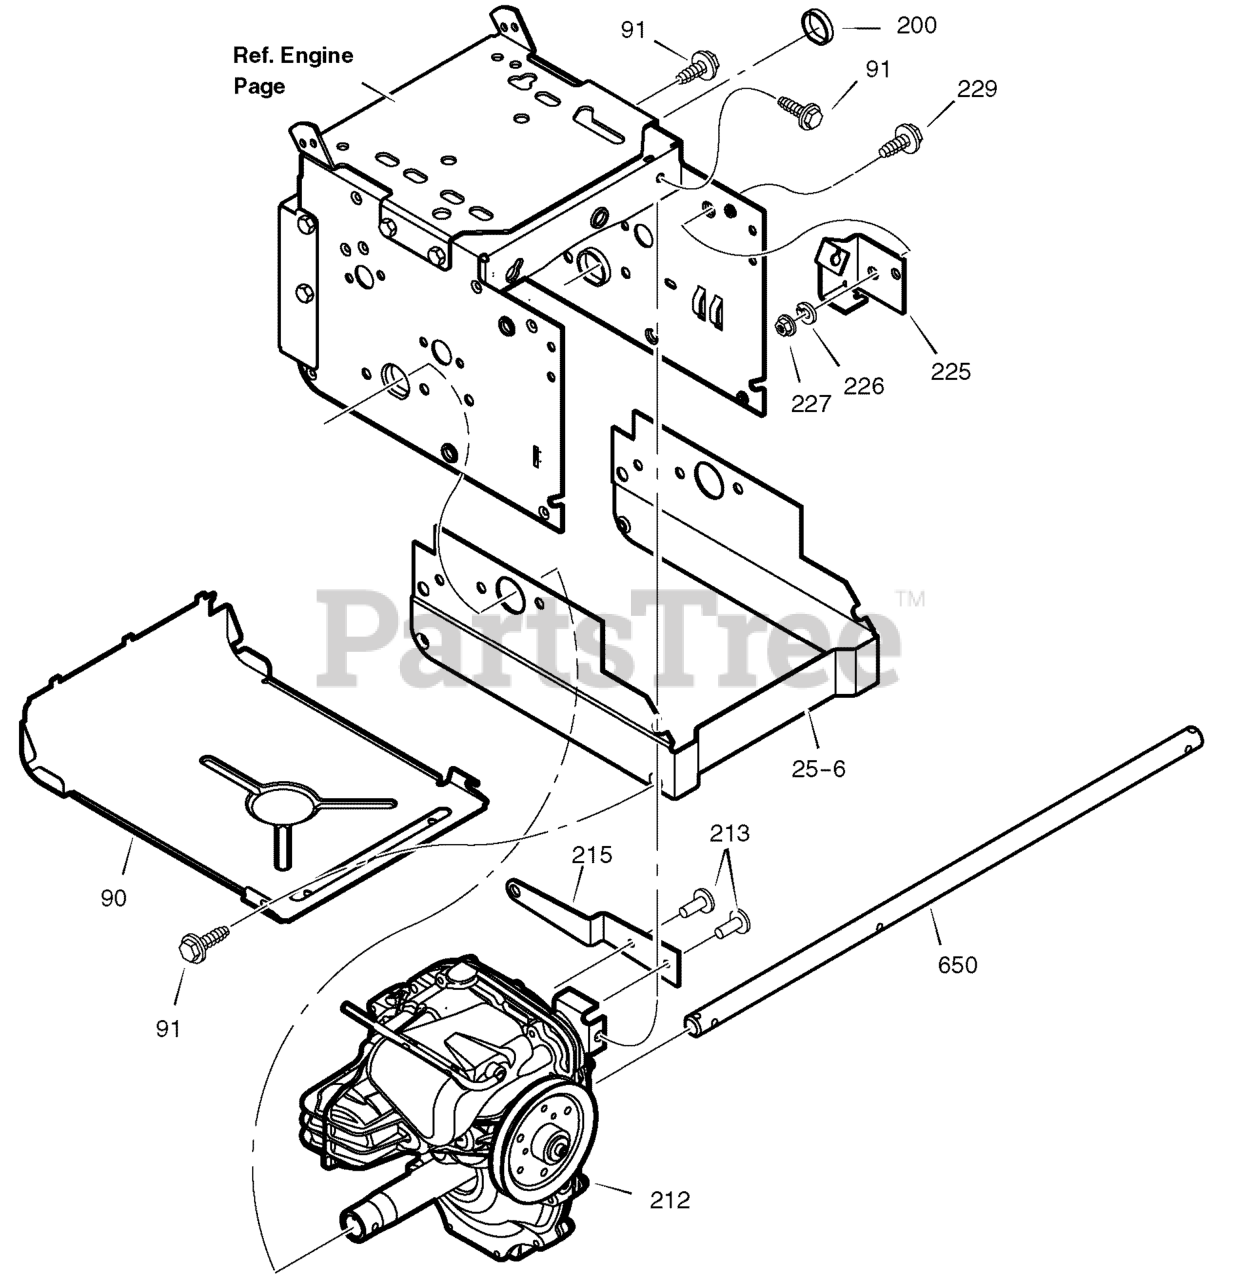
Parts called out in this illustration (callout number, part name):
25-6	FRAME, EXTENSION -- HYDRO
90	COVER, BOTTOM
91	SCREW, 1/4--20 X 0.62
200	PLUG, HEYCO
212	TRANSMISSION, HYDRO (314-0410) *
213	RIVET, BLIND
215	ARM, CONTROL EXTENSION
225	BRACKET, DRIVE CABLE
227	NUT, HEX JAM -- 3/8--16
650	AXLE, WHEEL
